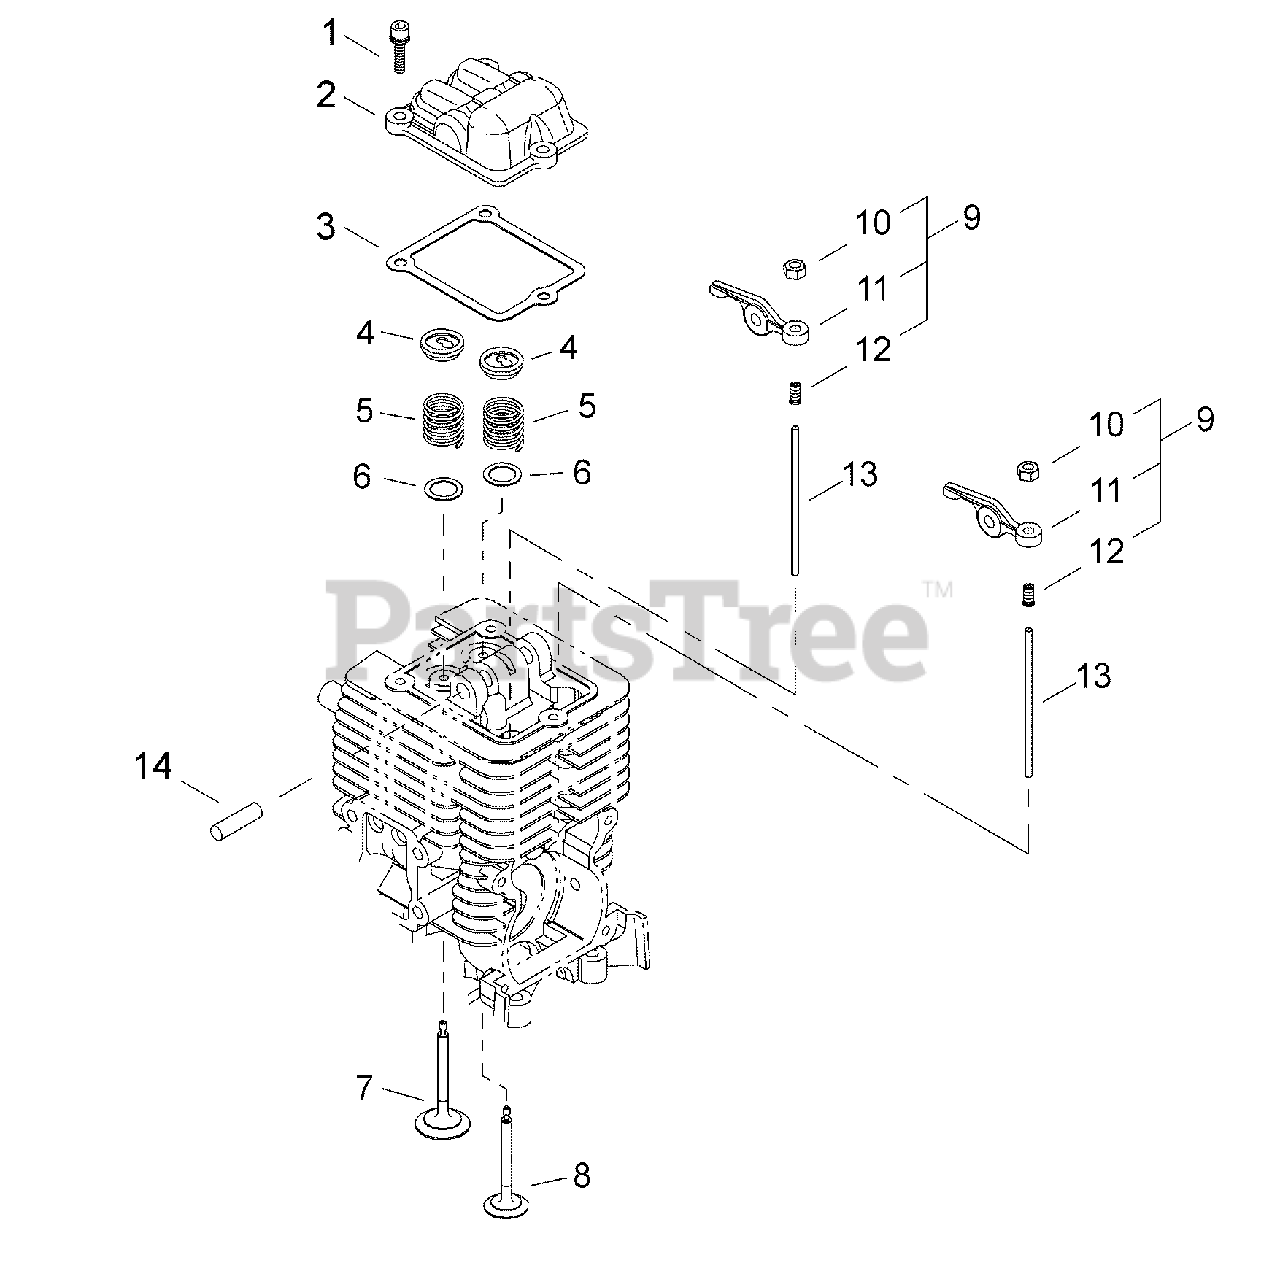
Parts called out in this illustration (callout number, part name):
1	BOLT M4×14
2	COVER, ROCKER ARM
3	GASKET, ROCKER ARM
4	RETAINER, VALVE
5	SPRING, VALVE
6	WASHER, VALVE 9
7	VALVE, INTAKE
8	VALVE, EXHAUST
9	ARM ASSY, ROCKER
10	NUT, ADJUSTER LOCK 5
11	ARM, ROCKER
12	SCREW, ADJUSTER
13	PUSHROD
14	SHAFT, ROCKER ARM Ø5×37.8 MM
